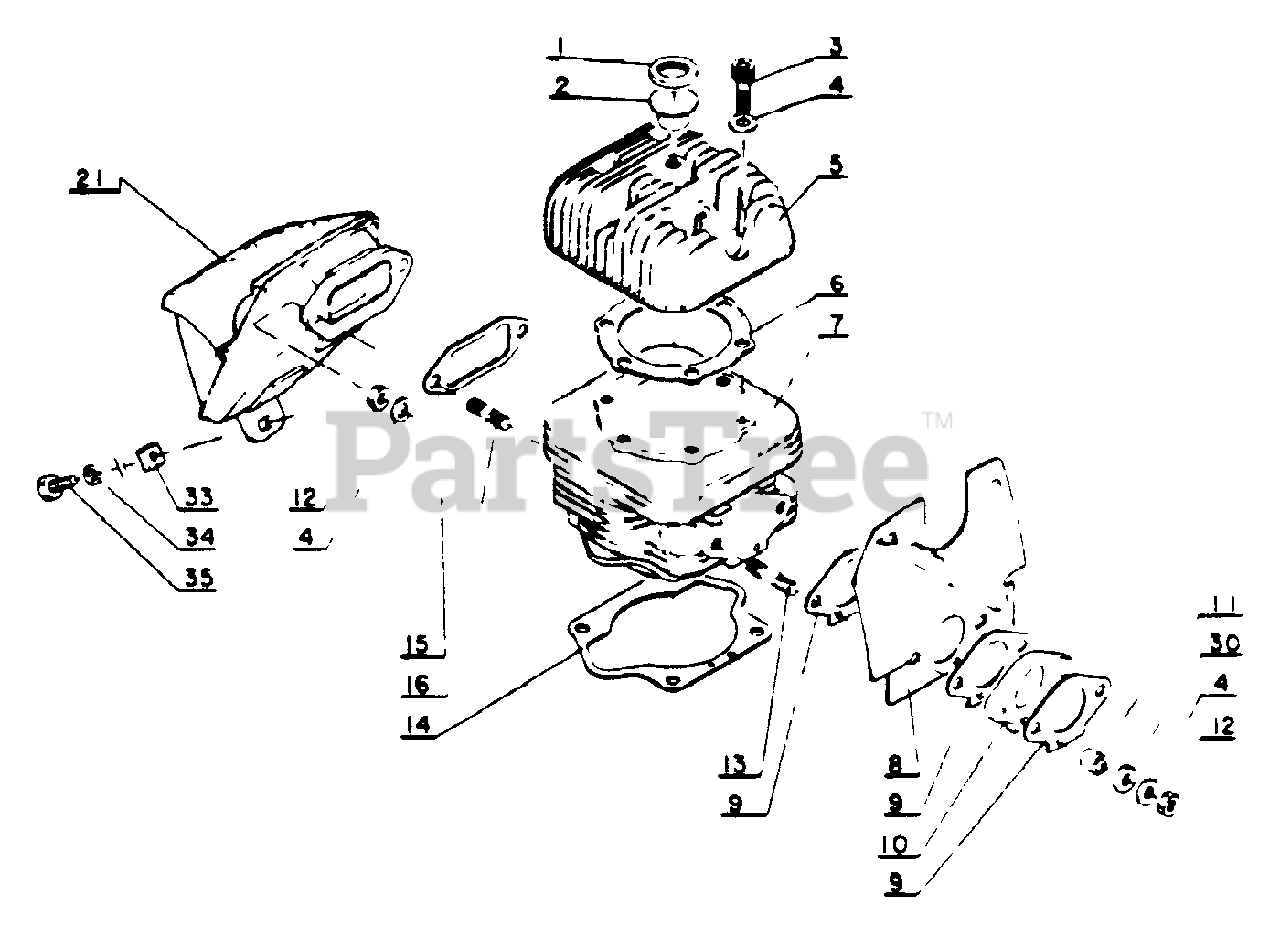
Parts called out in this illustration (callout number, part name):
1	INSULATOR
2	INSULATOR
3	BOLT - 6X22
4	WASHER - 6
5	HEAD, CYLINDER
6	GASKET, CYLINDER
7	CYLINDER
8	SHIELD, INTAKE
9	GASKET, INTAKE
10	INSULATOR, INTAKE
11	SPACER
12	LOCKNUT - 6
13	STUD
14	GASKET, CYLINDER
15	GASKET, EXHAUST
16	STUD
21	MUFFLER
30	INSULATOR
33	NUT
34	LOCKWASHER - 5
35	BOLT
35	BOLT - 5X12
